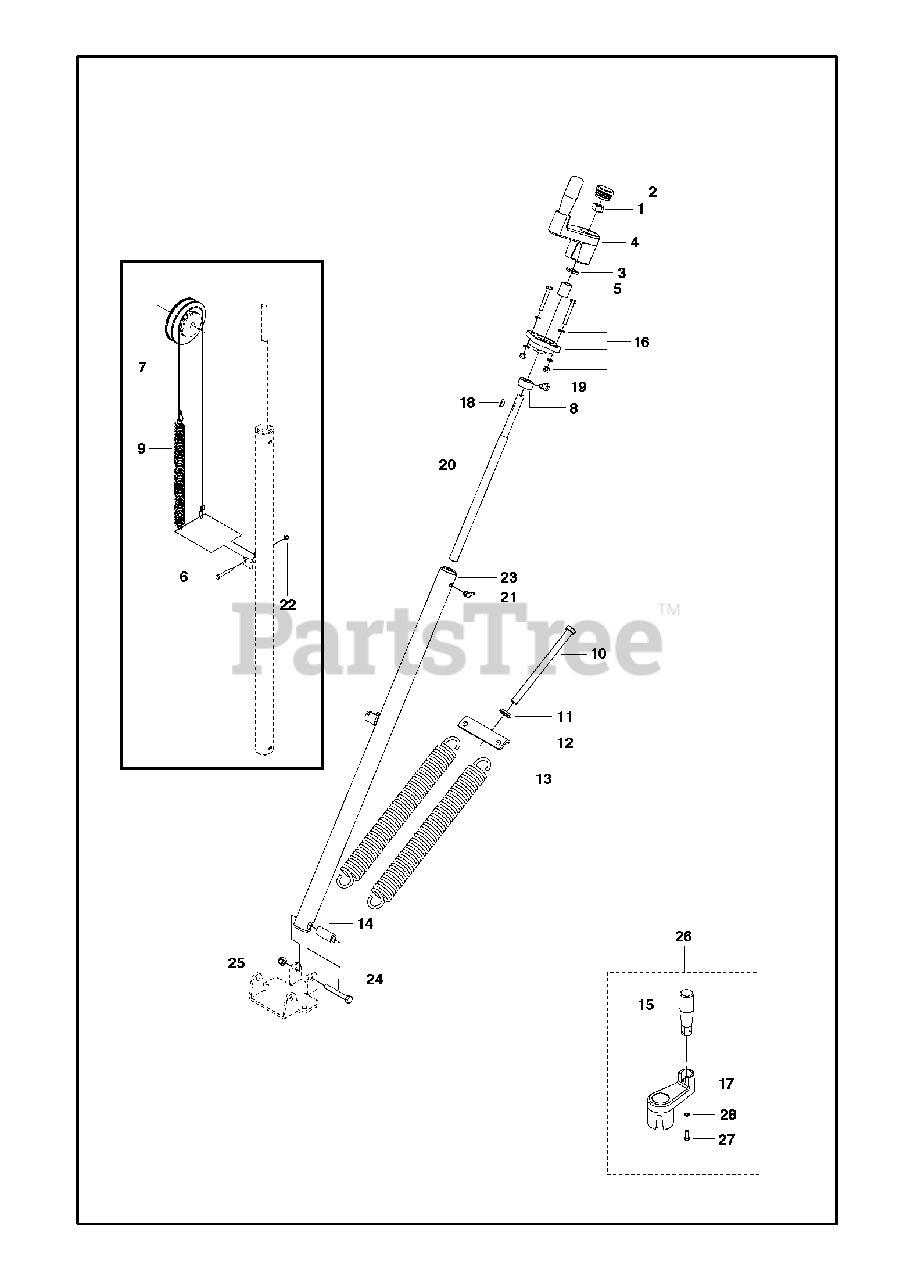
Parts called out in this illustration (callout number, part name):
3	WASHER
11	WASHER
22	HEXAGON LOCKING NUT
25	HEXAGON LOCKING NUT
